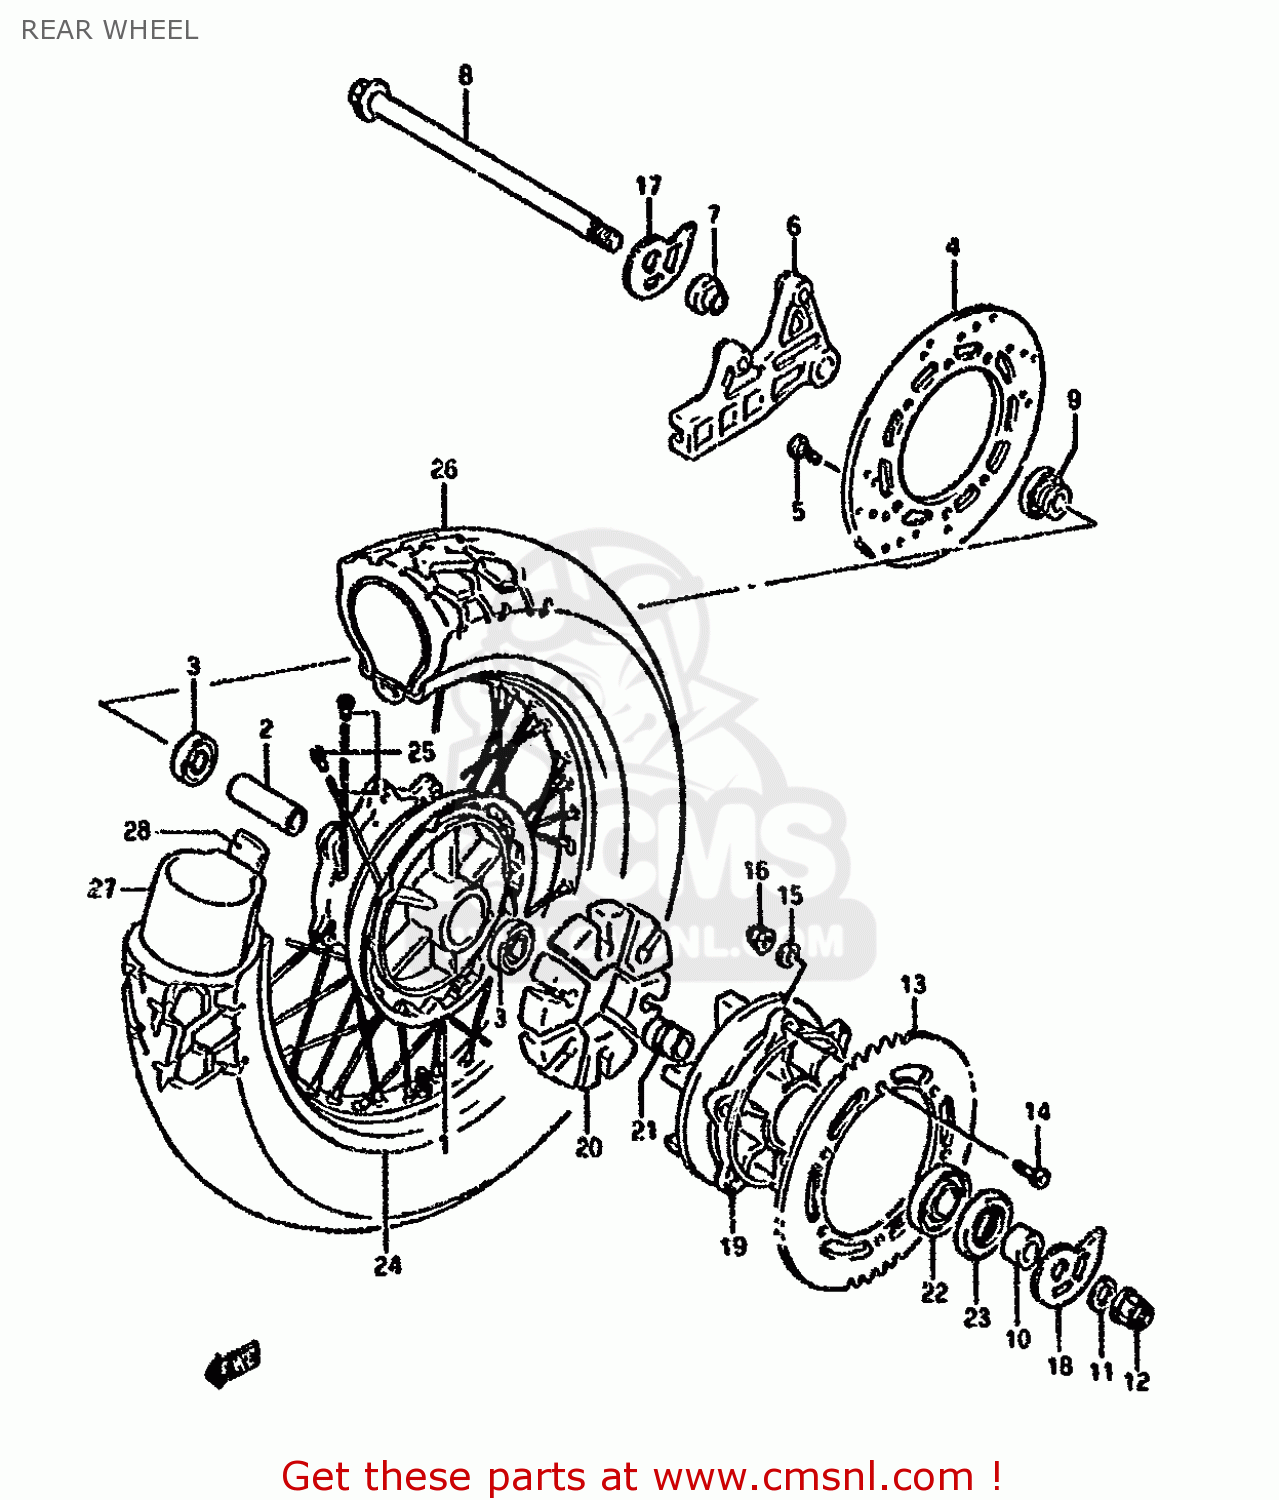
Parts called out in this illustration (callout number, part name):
1	HUB,REAR WHEEL
2	SPACER(17.5X25X78)
3	BEARING
4	DISC,RR BRAKE
5	BOLT,BRAKE DISC
6	BRACKET,RR CALIPER
7	SPACER (17X21X10)
8	AXLE, REAR
9	SPACER,RR AXLE,L
10	SPACER(17X33X22.4)
11	WASHER (17X30X3.2)
12	NUT
13	SPROCKET,RR(47T)
14	BOLT(8X30.5)
15	WASHER
16	NUT
17	ADJUSTER,CHAIN,R
18	ADJUSTER,CHAIN,L
19	DRUM,RR SPROCKET
20	ABSORBER,RR HUB SHOCK
21	RETAINER,RR SPROCKET DRUM
22	BEARING(25X62X17)
23	SEAL,OIL(33X62X7)
24	RIM,RR WHEEL(17XMT2.50)
25	SPOKE SET,RR
26	TIRE,REAR 130/80-17 65
27	TUBE ASSY,WHEEL INNER
28	PROTECTOR,WHL INR TUBE
